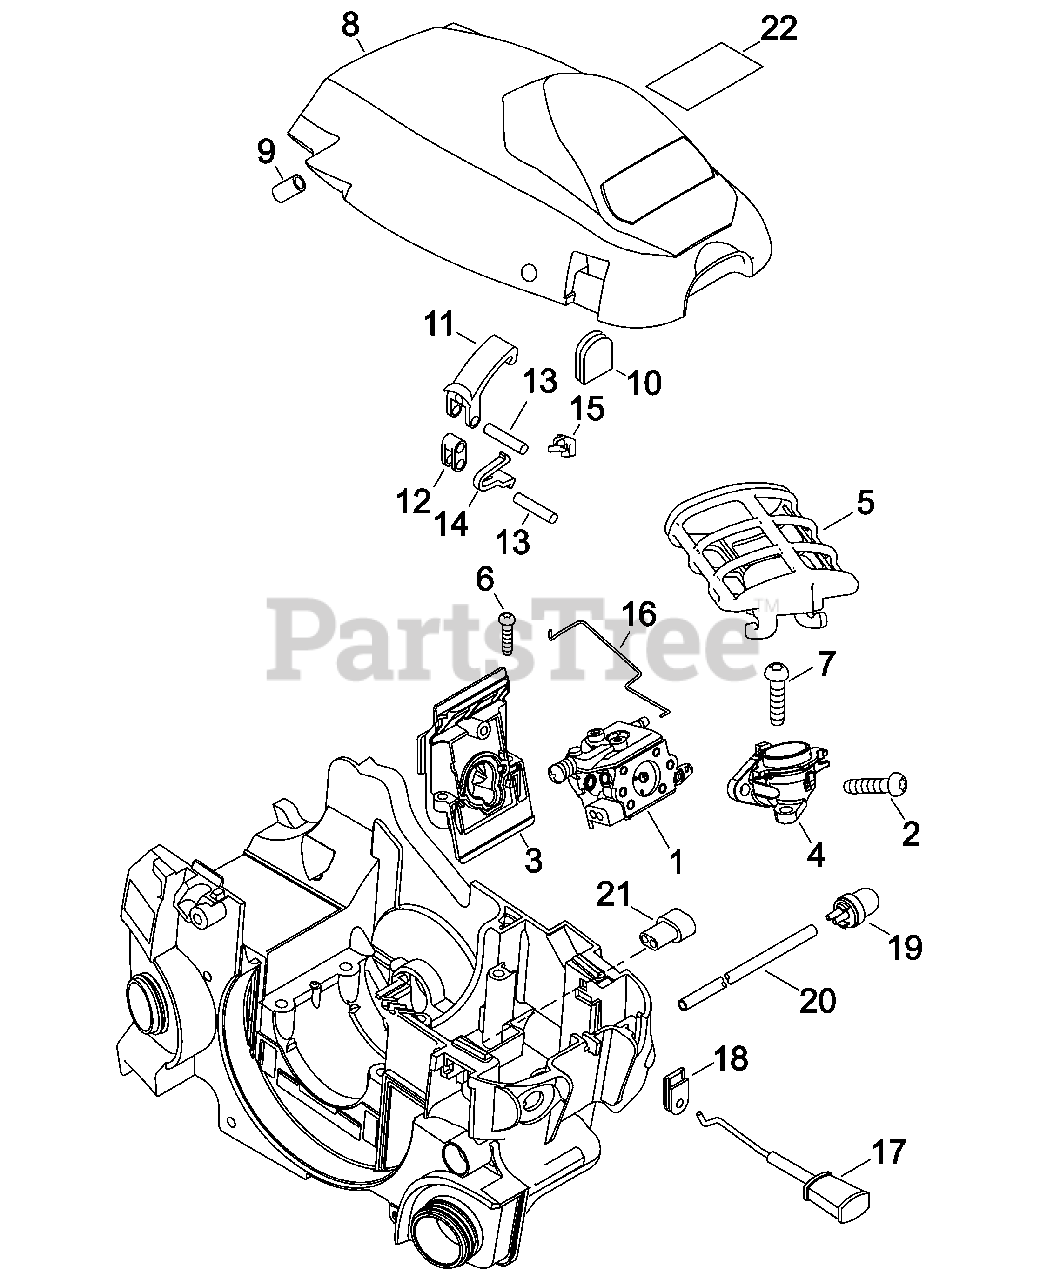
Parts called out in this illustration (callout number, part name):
1	CARBURETOR WT-1110
2	BOLT, TORX 5×55
3	INSULATOR, INTAKE
4	BRACKET, AIR FILTER
5	FILTER ASSY, AIR
6	BOLT, TORX 5×20
7	BOLT, TORX 5×16
8	COVER, ENGINE
9	BUSHING 3×7×10
11	LATCH, ENGINE COVER
13	PIN 4×17.8
15	STOPPER
16	ROD, THROTTLE
17	ROD, CHOKE
18	GROMMET, CHOKE
19	BULB, PURGE
20	PIPE 2.4×5×105 BLACK
21	GROMMET, NEEDLE
22	LABEL, MODEL
